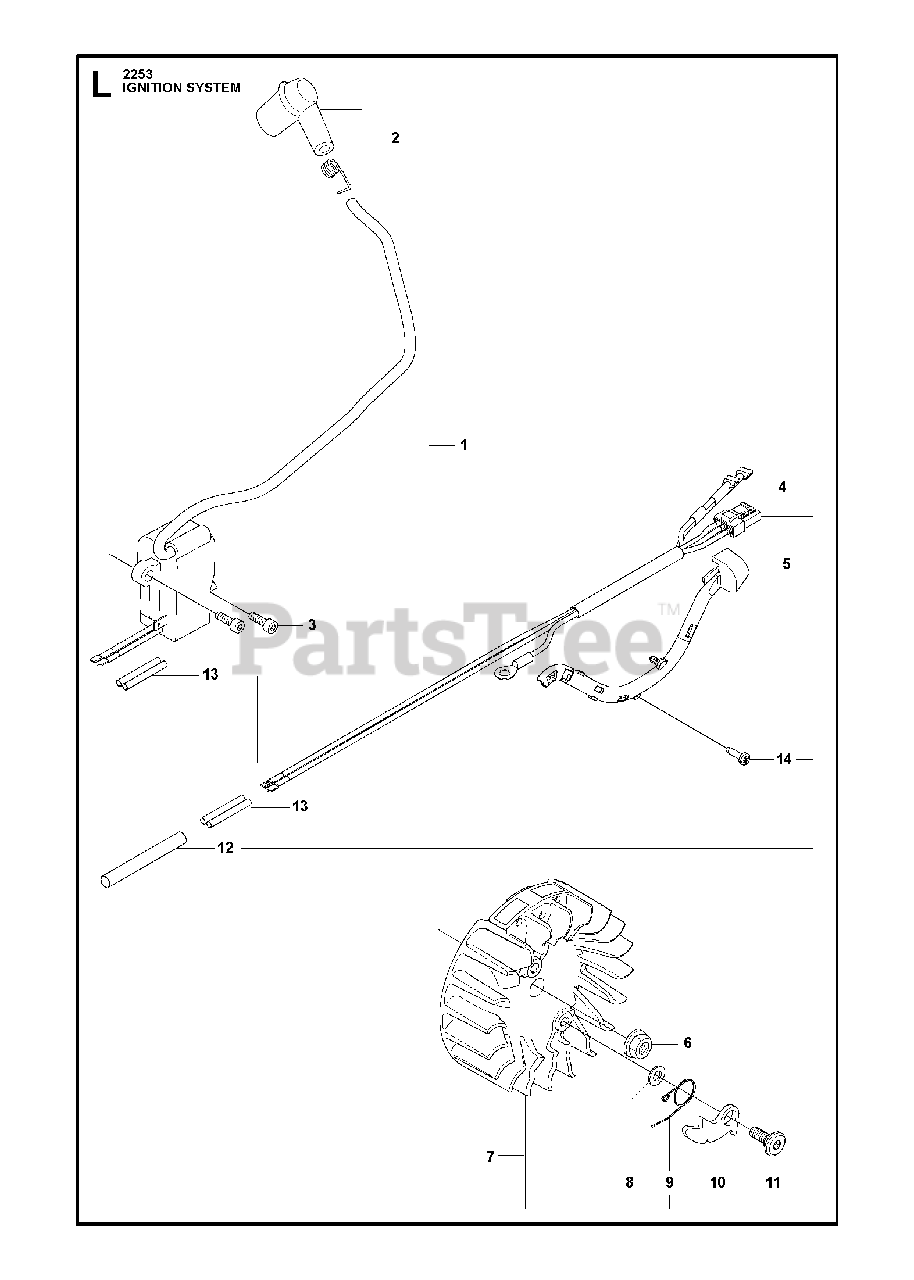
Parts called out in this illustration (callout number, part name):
1	RP IGNITION MODULE ASSY
2	SPARK PLUG CAP ASSY
4	WIRING ASSY
5	CABLE HOLDER
6	NUT W/ WASHER
7	FLYWHEEL ASSY
8	WASHER
9	SPRING
10	PAWL
11	SCREW M5X14
12	CABLE COVER
13	SHRINK HOSE
14	SCREW
